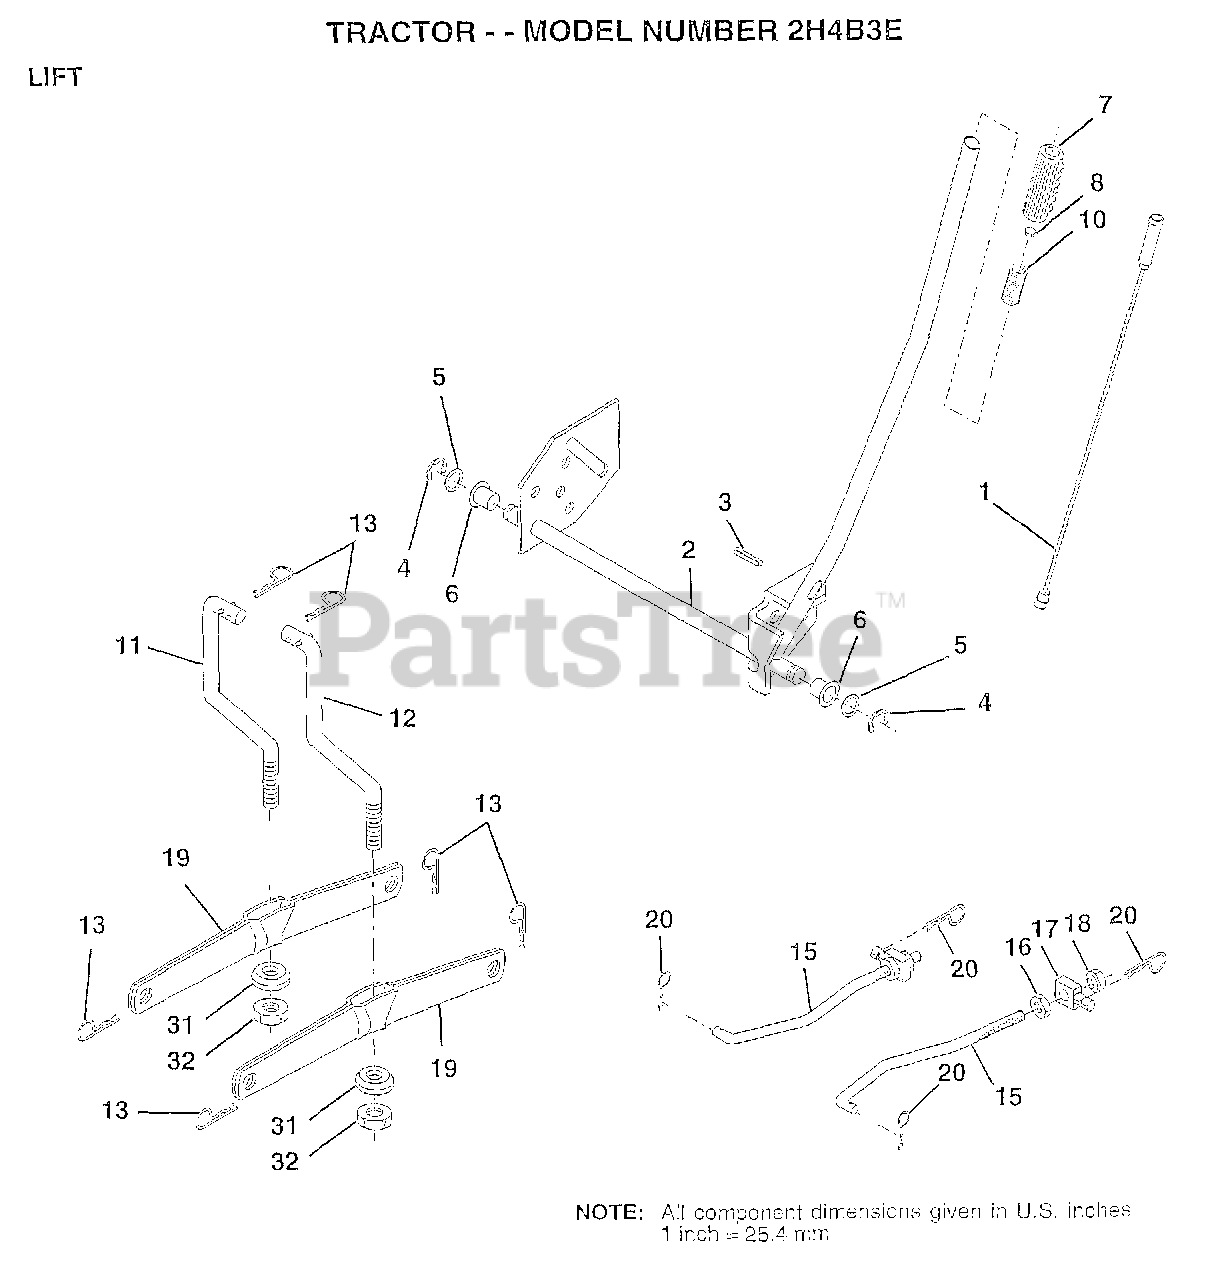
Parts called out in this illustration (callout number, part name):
1	WIRE ASM
3	PIN-GROOVE LT
5	WASHER
6	NYLON BEARING
7	GRIP
15	LINK.FRONT
16	NUT
17	TRUNION
18	NUT.LK.W/WSH.1/2.
19	ARM SUSP REAR
20	RETAINER.SPRING
31	BEARING PVT LH
32	NUT.CROWNLOCK.3/8
